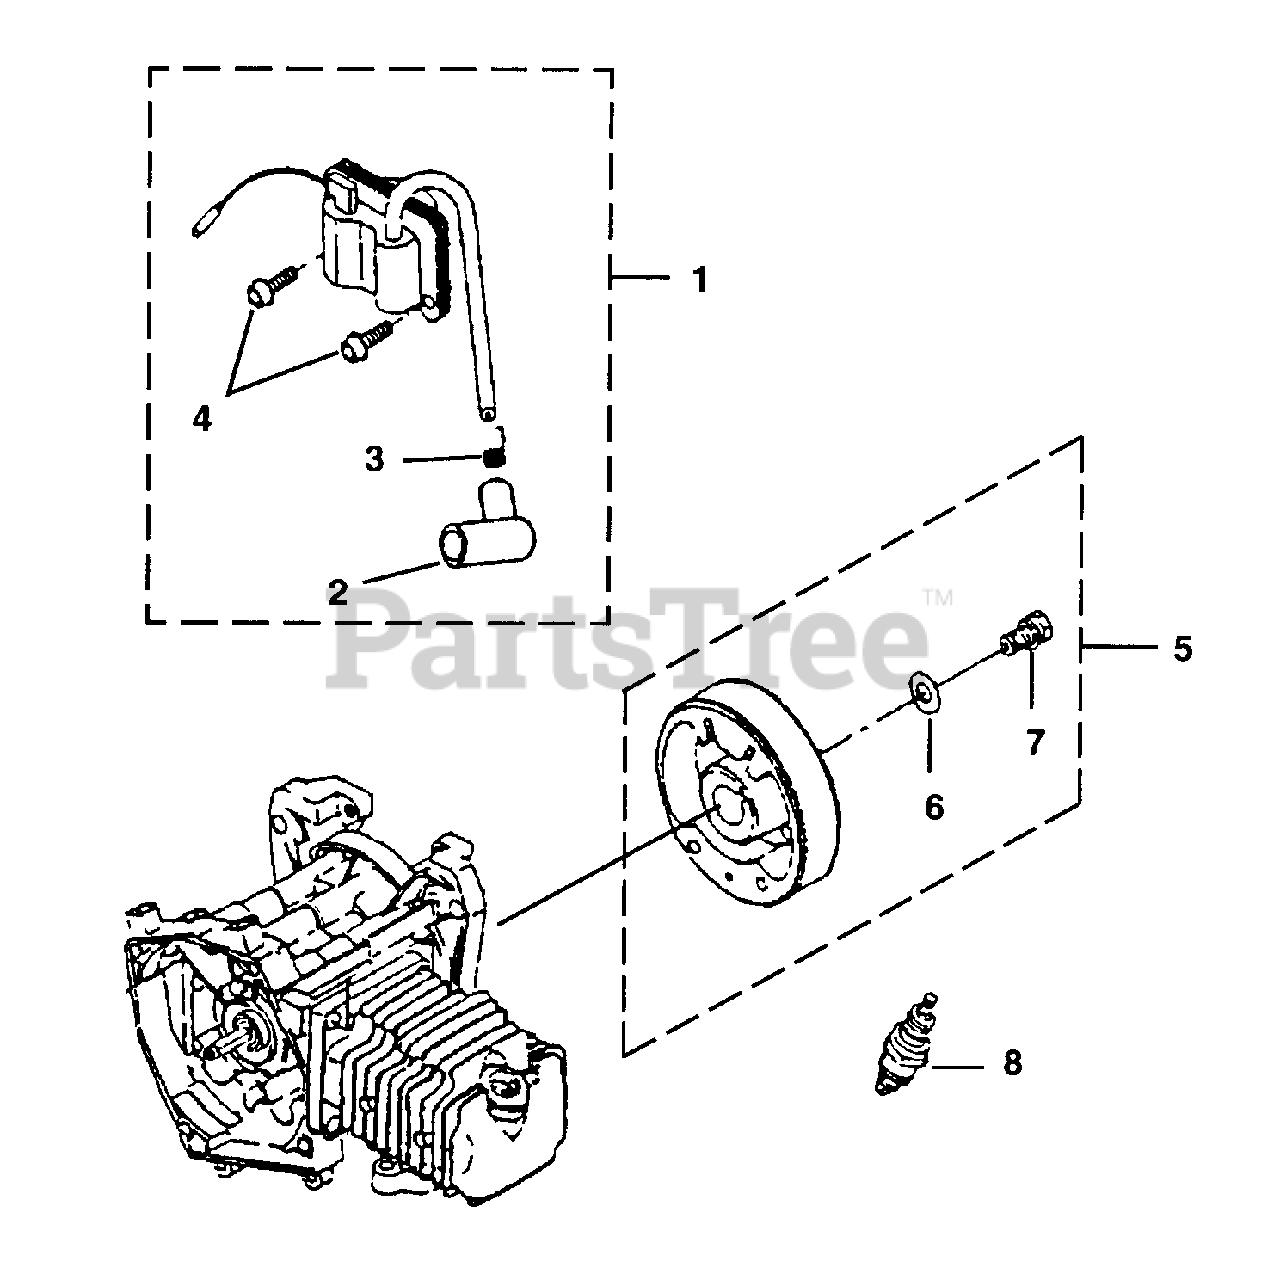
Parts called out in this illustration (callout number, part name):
1	IGNITION KIT
2	CAP-Plug
3	SPRING-Plug Cap
4	SCREW-Socket Hd (M5 x 22 W)
5	ROTOR ASSEMBLY
6	WASHER (M8)
7	BOLT ASSEMBLY (MS x 16 SW)
8	SPARK PLUG
